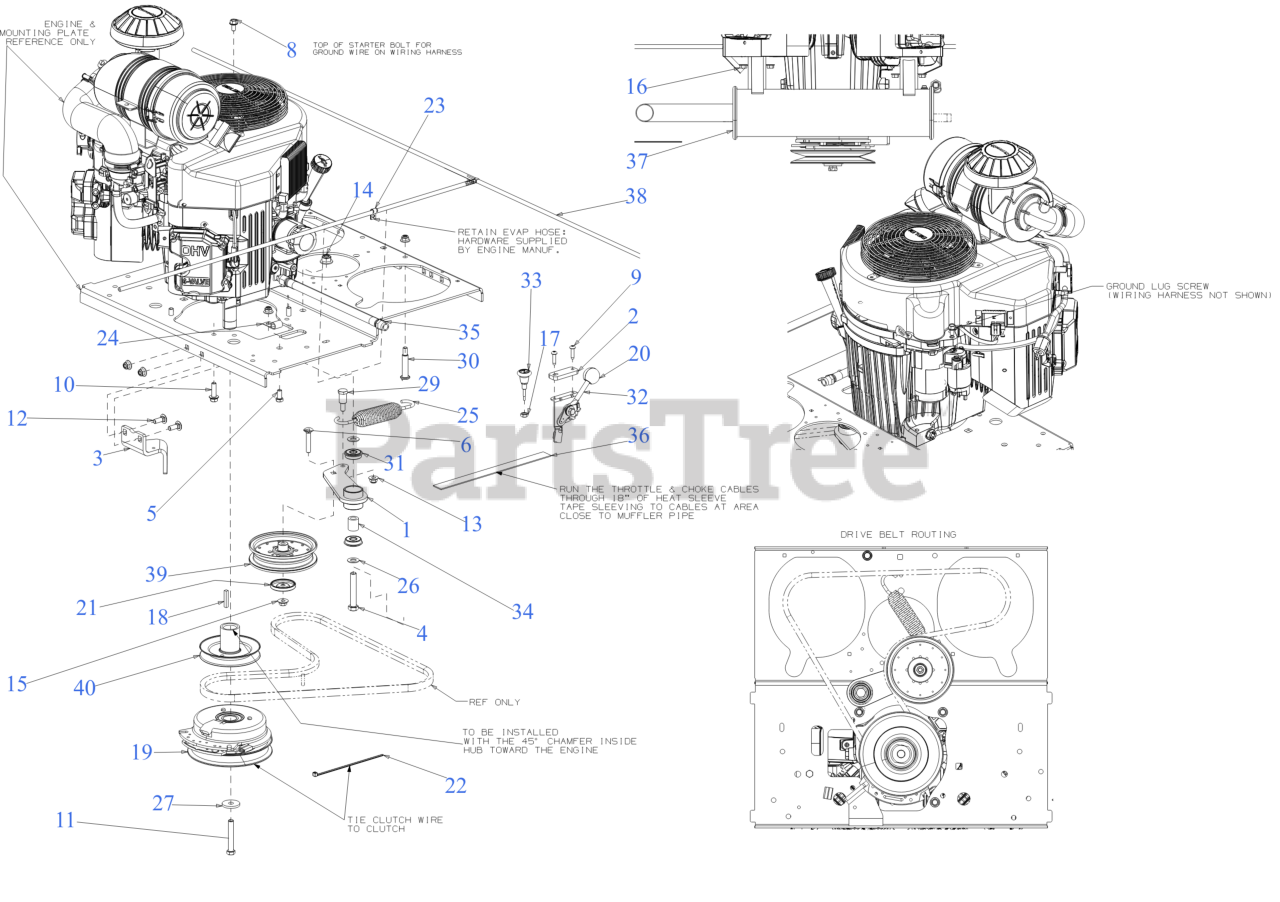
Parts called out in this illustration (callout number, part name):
1	IDLER BRACKET
3	CLUTCH RETAINER BRACKET
4	SCREW-HEX 1/2-13 x 3.00
5	HEX SCREW 3/8-16 x .75
6	CARRIAGE BOLT 3/8-16 x 2
7	SCREW 7/16-20:2.75 GR5
8	SCREW M8 x 1.25 x 16MM GR8.8
9	SCREW 1/4-20 x 1.0
10	SCREW 3/8-16 x 1.25 GR5
11	SCREW 7/16-20 x 3.25 GR5
12	CARRIAGE BOLT 3/8-16 x 1.00 GR5
15	FLANGE LOCK NUT
16	HEX FLANGE NUT
17	HEX JAM NUT 3/8X24
18	SQUARE KEY 1/4 x 1.50
19	ELECTRIC PTO CLUTCH
21	PULLEY CAP
22	7" CABLE TIE
23	MOUNTING CLAMP
24	J TYPE CLIP
25	EXTENSION SPRING W/HOOK
26	FLAT WASHER .510 x .995
27	FLAT WASHER .45 x 1.5 x .172 HT
29	SHOULDER SCREW .625 x .875 x 3/18
30	SHOULDER BOLT (.50 X 2.0 x 3/8 -16)
31	ROLLER BEARING .5X1.37X.44
32	THROTTLE CABLE 59"
33	CHOKE CABLE
34	SPACER 0.51 x 0.88 x 1.00
35	OIL DRAIN HOSE
36	HEAT SHIELD 24"
37	MUFFLER - KAWASAKI 1000
39	FLAT IDLER PULLEY
40	ENGINE PULLEY
